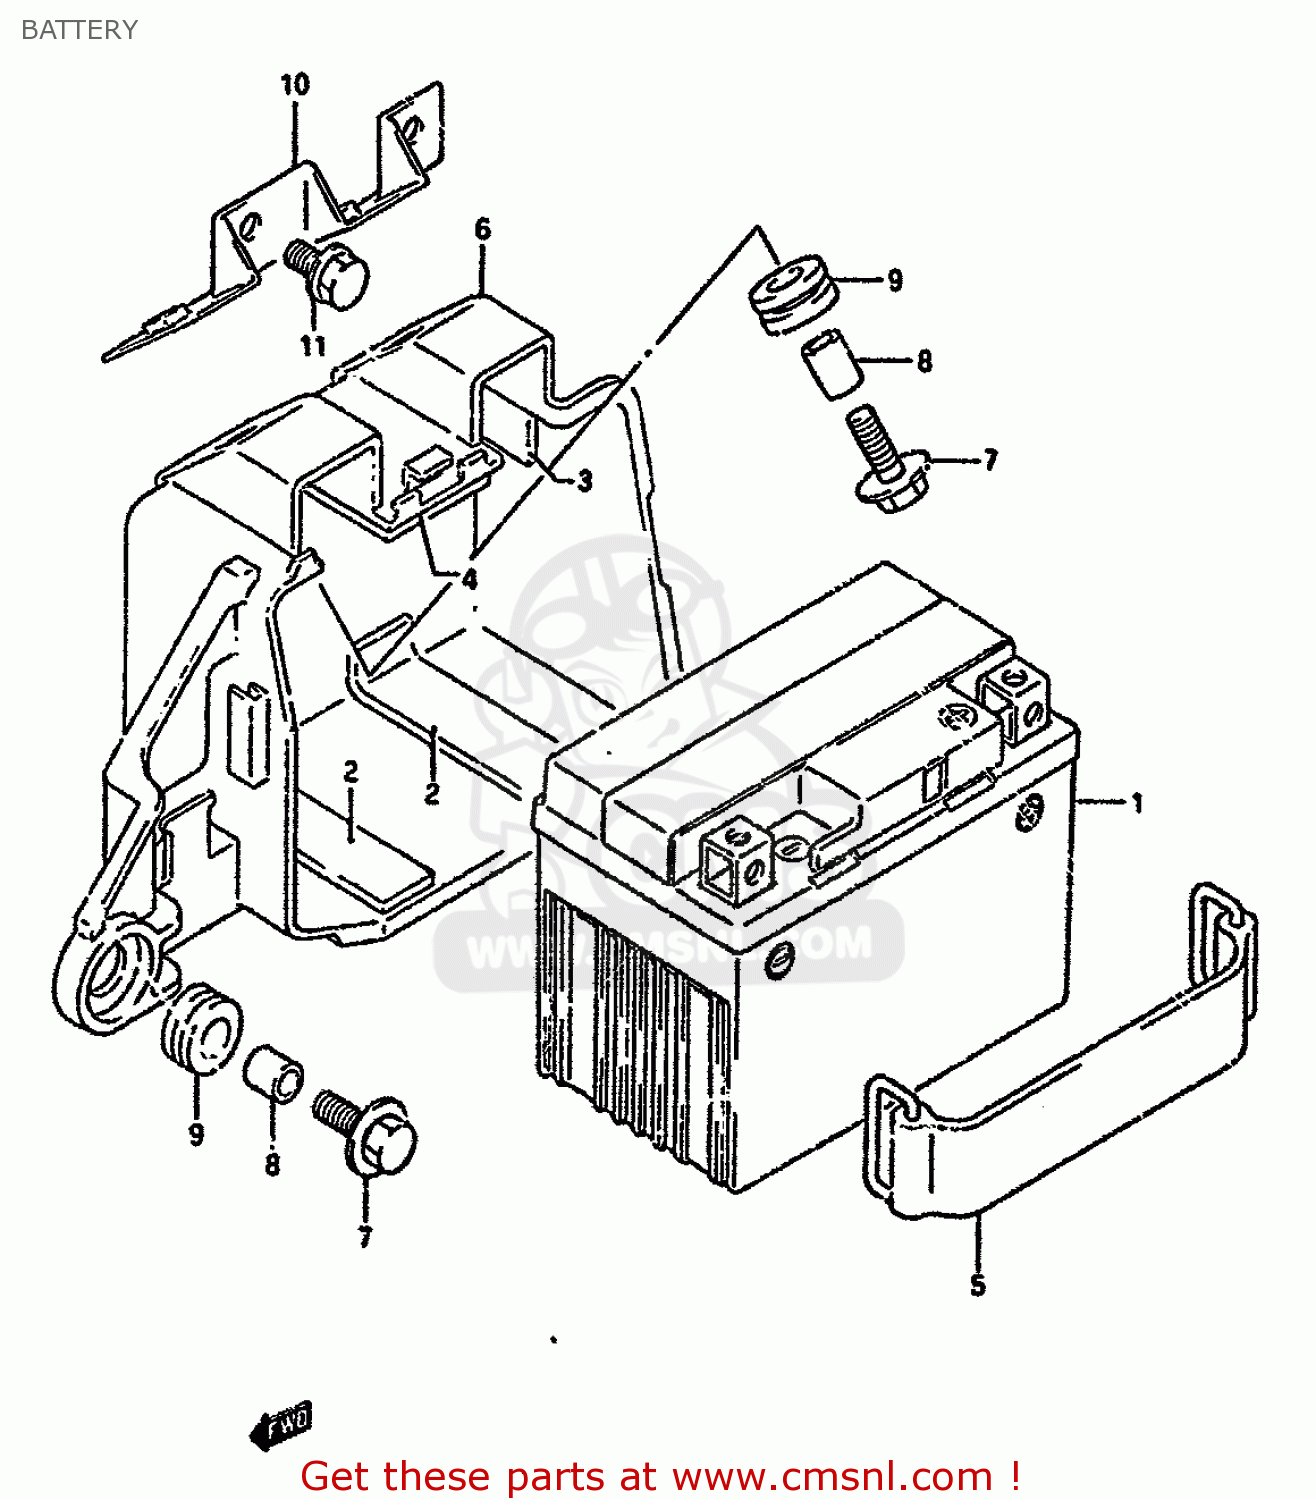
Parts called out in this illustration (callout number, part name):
1	BATTERY,YT4L-B
2	PROTECTOR,BATTERY
3	PROTECTOR,BATTERY
4	PROTECTOR,BATTERY
5	BAND
6	HOLDER,BATTERY
7	BOLT(6X20)
8	SPACER
9	CUSHION
10	PLATE COMP,BATTERY HOLDER
11	BOLT
